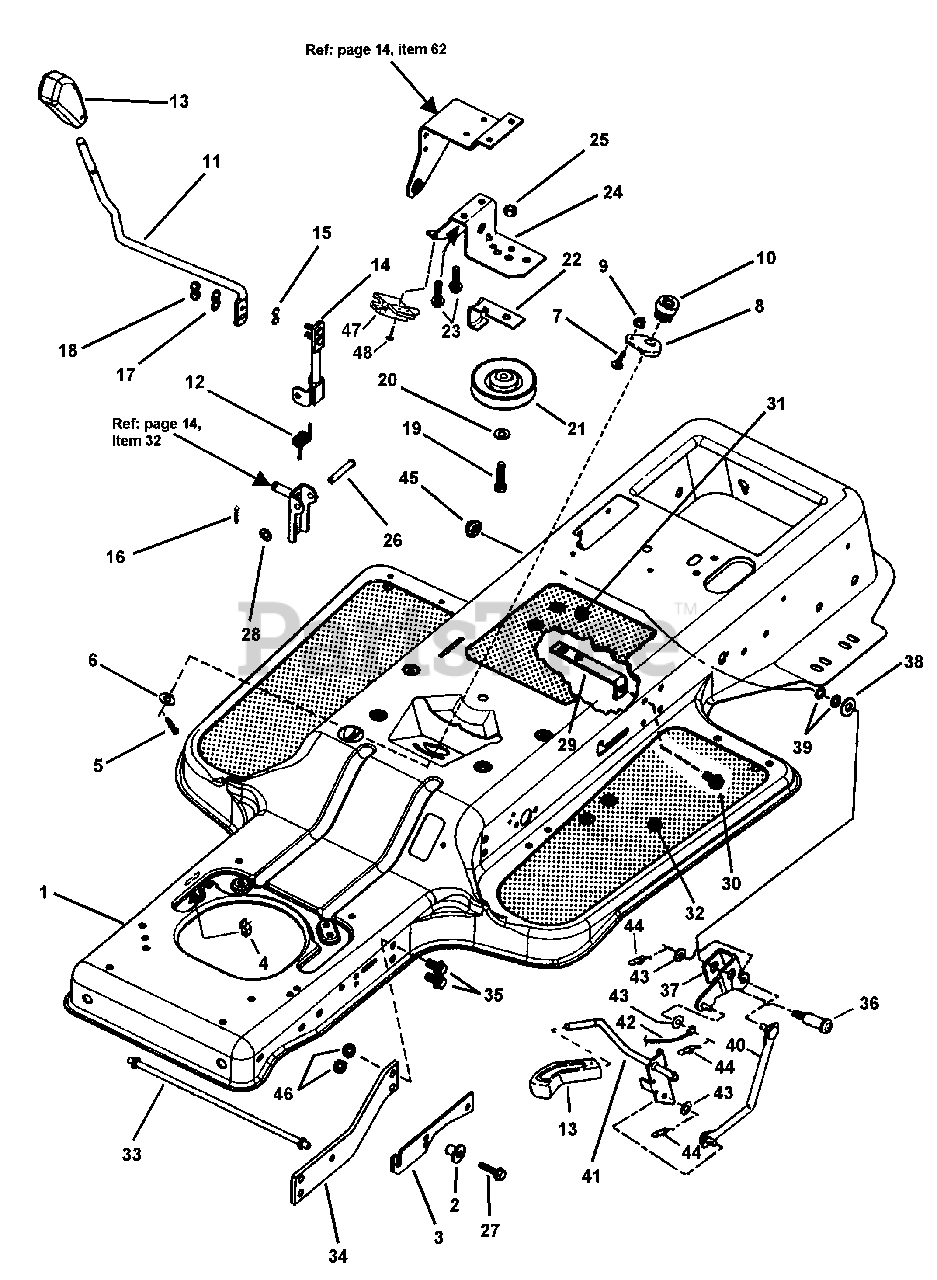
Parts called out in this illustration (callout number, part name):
1	FRAME, Tractor (1 Piece)
2	BUSHING, Flange
3	BRACKET, Hood Pivot
4	CLIP, Wire
5	COTTER-PIN, 1/8 x 3/4"
6	WASHER, 1/2 Shim
7	BOLT, 1/4-20 x 5/8" Short Neck Carriage, Grade 5
8	ASSEMBLY, Steering Adjuster
9	NUT, 1/4-20 Hex Flange Lock, Grade 5
10	GEAR, Steering Pinion
11	LEVER, Shift (Upper)
12	SPRING, Shift Torsion Shift Lever
13	KNOB, Deck Lift Lever
14	WELDMENT, Shift Lever (Upper)
15	WASHER, 1/4 Internal Tooth Lock
16	COTTER-PIN, 5/32 x 1"
17	WASHER, 1/4 Flat
18	NUT, 1/4-20 Hex Nyloc
19	SCREW, 3/8-16 x 1-1/2" Hex Head Cap, Grade 5
20	WASHER, 3/8" Flat
21	PULLEY, Idler
22	GUIDE, Pulley Belt
23	SCREW, 5/16-18 x 1-1/4" Swage
24	SUPPORT, PTO Lever
25	NUT, 3/8-16 Hex Center Lock, Grade 5
26	PIN, 5/16 x 1.73" Clevis
27	SCREW, 5/16-18 x 1-1/4" Self-Tapping
28	WASHER, 5/16" Flat
29	ANCHOR, Blade Brake
30	SCREW, 3/8-16 x 5/8" Hex Washer Self-Tap
31	DECAL, Instruction Frame Top
32	PAD, Foot (Rubber Deluxe)
33	GUIDE, Belt
34	BRACE, Frame
35	BOLT, 3/8-16 x 3/4" Hex Flange Lock
36	BOLT, 1/2-13 Thread Shoulder
37	WELDMENT, Bellcrank PTO
38	WASHER, Thrust
39	WASHER, 1/2" Internal Tooth Lock
40	WELDMENT, PTO Link
41	WELDMENT, PTO Lever
42	CABLE, 33 Blade (33" Deck)
43	WASHER, 7/16" Flat
44	COTTER PIN, 3/8 Self-Lock
45	NUT, 1/2-13 Hex Flange Lock, Grade 5
46	NUT, 3/8-16 Hex Flange Lock
47	SWITCH, NO/NC
48	SCREW, #10-24 x 1/2" Hex Washer Self-Tap (Torx)
